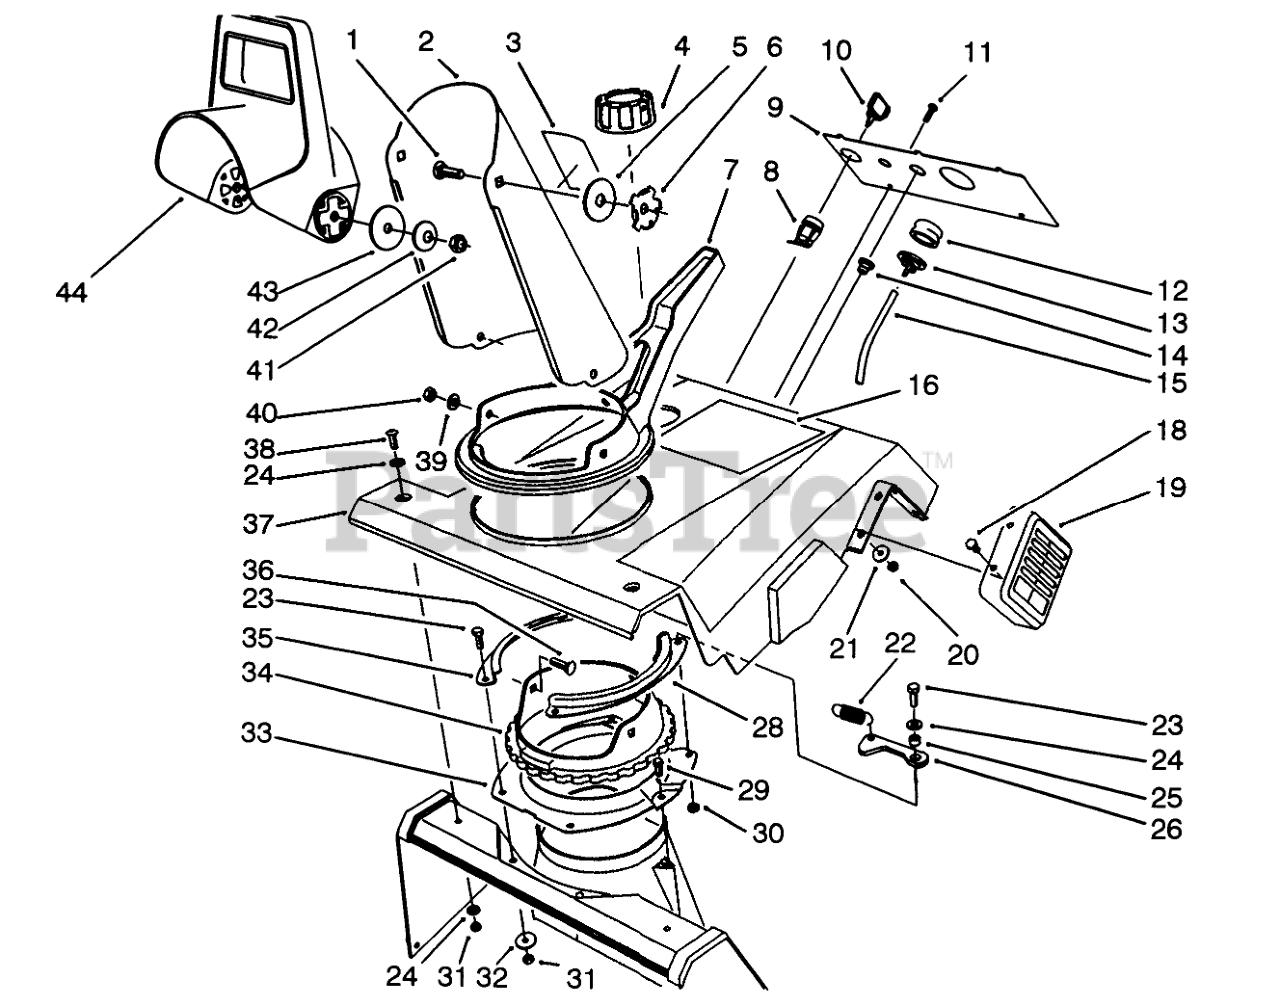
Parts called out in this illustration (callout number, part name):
1	SCREW-CARR
2	Chute
3	Decal-Danger
4	CAP-FUEL ASM
5	WASHER-RUBBER
6	PLATE-FRICTION
7	CHUTE - HANDLE
8	SWITCH
9	CNTRL PANEL/SILK SCREEN
10	KEY-IGNITION
11	SCREW-SHWH, THREAD FORMING
12	BULB-PRIMER
13	BODY-PRIMER
14	GUIDE-ROPE, STARTER
15	HOSE-PRIMER
16	DECAL - CCR1000
18	SCREW-HWH
19	Guard-Muffler
20	NUT-LOCK, NI
21	WASHER-FLAT
22	OBS DETENT SPRING
23	SCREW-HH
24	WASHER-FLAT
25	SPACER-BLADE, ROTOR
26	DETENT
28	Retainer-Chute Ring
29	SCREW-PLASTITE
30	NUT-LOCK, NI
31	NUT-LOCK, NI
32	WASHER-FLAT
33	Ring-Chute Support
34	GEAR RING, CHUTE
35	Retainer-Chute Ring
36	SCREW-CARR
37	PINION ASM
38	SCREW-PPH
39	WASHER-FLAT
40	NUT-KEPS
41	NUT-LOCK, NI
42	WASHER-BELLEVILLE
43	WASHER-FLAT
44	CHUTE-DEFLECTOR
